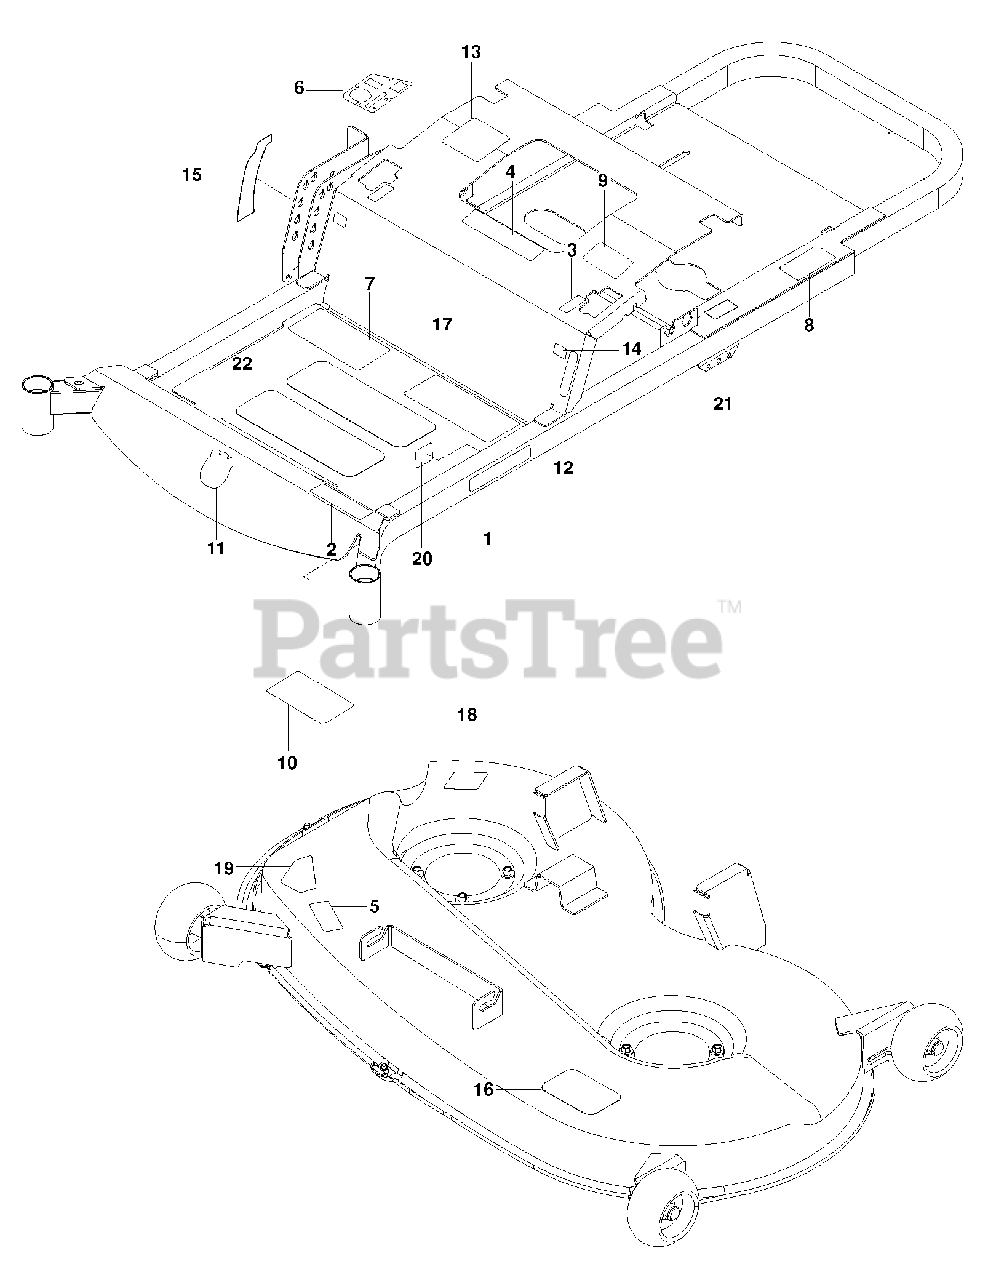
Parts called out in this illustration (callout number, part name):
1	RP.DECAL.BADGE.170MM.TEXTLOGO
3	DECAL, MOTION CONTROL
4	EURO DECAL-BATTERY WARNIN6
5	DECAL, EURO SEVERING
6	DECAL.ZTR.CONTROL.PANEL.HUSQV
7	DECAL.ZTR.STRTNGINS.SMARTIGNIT
8	DECAL, DO NOT TOW
9	DECAL, EXITING MOWER
10	DECAL, SERVICE
11	DECAL.AUGER.HUSQ.CROWN.SNOW
12	DECAL, PARK BRAKE
13	DECAL, CUSTOMER RESPNSIBILITY
14	DECAL, F.S.T.
15	DECAL, DECK HEIGHT, HUSQ
16	DECAL, BELT ROUTING
17	DECAL.ZTR.WARNING.SMARTIGNITIN
18	DECAL.DECK.6MIL./DEF.SHLD.WARN
19	DECAL, CPSC
20	DECAL, ECM, AUSTRALIA
21	DECAL.80.DBA.AUSTRALIA
22	ANTI-SKID PAD
